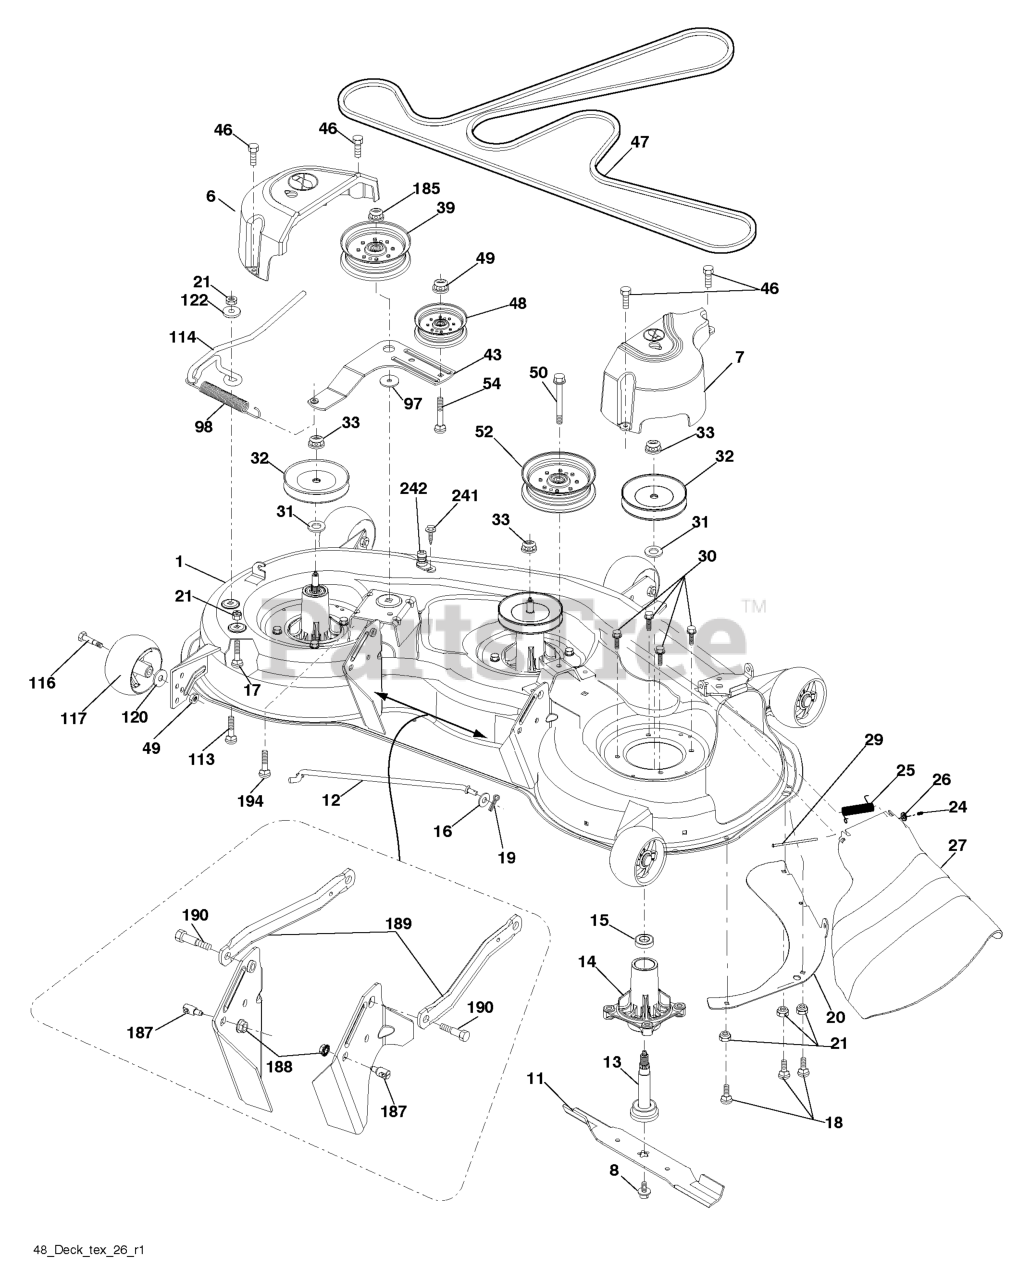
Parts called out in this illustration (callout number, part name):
1	DECK.PNT.WELDMENT.48"T
6	COVER.MANDREL.LH.48"(2 2)
7	COVER.MANDREL.RH.48"
8	BOLT.WASHER.ASM.7/16-2
11	48" HI-LIFT BLADE
12	ROD.ANTI.SWAY.48/54"K4
13	SHAFT ASM MANDREL
14	RP.HOUSING.MANDREL.4PT.
16	WASHER
17	BOLT.CARR.5/16-18X5/8.SHORT
18	BOLT
19	PIN.COTTER.5/16.BOW TI
20	BAFFLE, VORTEX MWR
21	LOCKNUT
24	CAP-SLEEVE LT
25	SPRING, TORSION
26	NUT PUSH M
27	DEFLECTOR SUBS TO 532 180655
29	ROD.HINGE
30	SCREW, WASHER HEAD
31	WASHER.SPACER.MANDREL
32	PULLEY MANDREL
33	NUT.FLANGE.LOCK.TOP
39	RB PULLEY.IDLER.4.50/HUB SPEC
43	ARM.IDLER
46	SCREW.1/4-20X5/8
47	BELT.DRIVE.DECK
48	PULLEY.IDLER.2006
49	NUT LOCK FLG 3/8-16 UNC
50	SCREW TT 3/8-16X2-1/4 UNC
52	PULLEY.IDLER.48"PRIMARY
54	BOLT.3/8-16X1.50
98	SPRING, DECK DRIVE
113	BOLT CRT
114	ROD.TENSION.RELIEF.TEX (2 2)
116	BOLT.SHOULDER.3/8-16X3-5/8.
117	RP WHEEL. GUAGE RALLY
120	WASHER
122	BUSHING.RELIEF.TENSION
185	NUT.LOCK.FLANGE.7/16
187	STUD.FASTNER.W/ANTI-ROTATE
188	NUT LOCK HEX FLANGE 5/16-18
189	ARM.SUSPENSION.MOWER
190	BOLT.SHOULDER
194	BOLT.CARR.SQNK.7/16
241	SCREW.TT.#10-32X.5.3/8.FLANGE
242	PORT.WASHOUT
